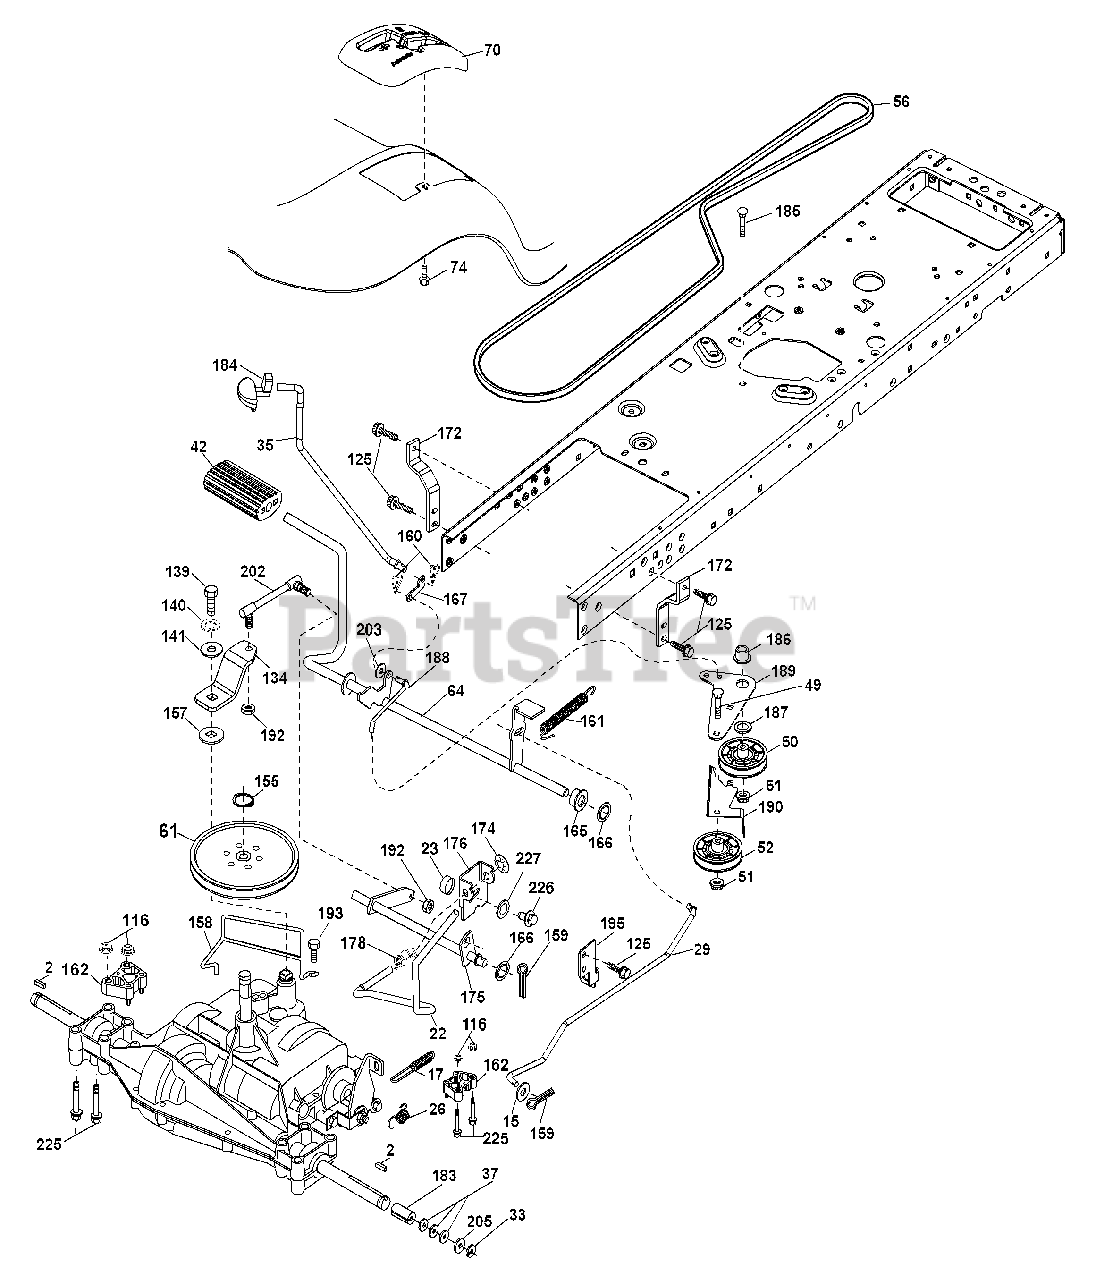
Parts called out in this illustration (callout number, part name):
2	Key Square
15	Washer 13/32 x 13/16 x 16 Ga.
17	Spring, Brake
22	Rod Shift
23	Knob
26	Spring Brake RTN
29	Rod, Brake
33	Ring E
35	Rod, Brake, Park
37	Washer 25/32 x 1-1/4 x 16 Ga.
42	Cover, Foot Pedal
49	Bolt
50	Pulley Idler Flat
51	Lock Nut 3/8-16
52	Idler V-Groove
56	V-Belt, Drive
61	Pulley Transaxle
64	Shaft Asm. Pedal Brake Control
70	Console
74	Screw 1/4 x 1/2
116	Nut Lock Hex Flange 5/16-18
125	Screw 5/16-18 x 3/4
134	Arm Shift
139	Bolt 1/4-20 unf Gr. 8 w/Patch
140	Washer Lock Hvy Helical 1/4
141	Washer 9/32 x 3/4 x 10 Ga.
155	Ring Retainer
157	Washer Plate Shf
158	Keeper T/A
159	Pin Cotter 1/8 x 3/4
160	Retainer Clip
161	Spring, Return, Clutch
162	Spacer
165	Busing Shaft Brake Hand Control
166	Nut Push .625
167	Latch Brake Parking
172	Strap Torque LH
174	Nut Push
175	Shaft Asm Shift
176	Arm Clevis Rod Shift
178	Spring Shift
183	Spacer Axle
184	Handle Parking Brake
185	Bolt
186	Spacer Retainer
188	Link Clutch Ground Drive
189	Bellcrank Ground Drive
190	Keeper Bellcrank Ground Drive
192	Nut Lock Center 1/4-28
193	Screw 5/16-18 x 3/4
195	Bracket Brake Rod
202	Link Shift
203	Washer 11/32 x 11/16 x 16 Ga.
205	Washer 25/32 x 1-5/8 x 16 Ga.
225	Bolt 5/16-18 x 3.75
226	Bolt 7/16-14 x 1 Gr.5
227	Washer Serrated
